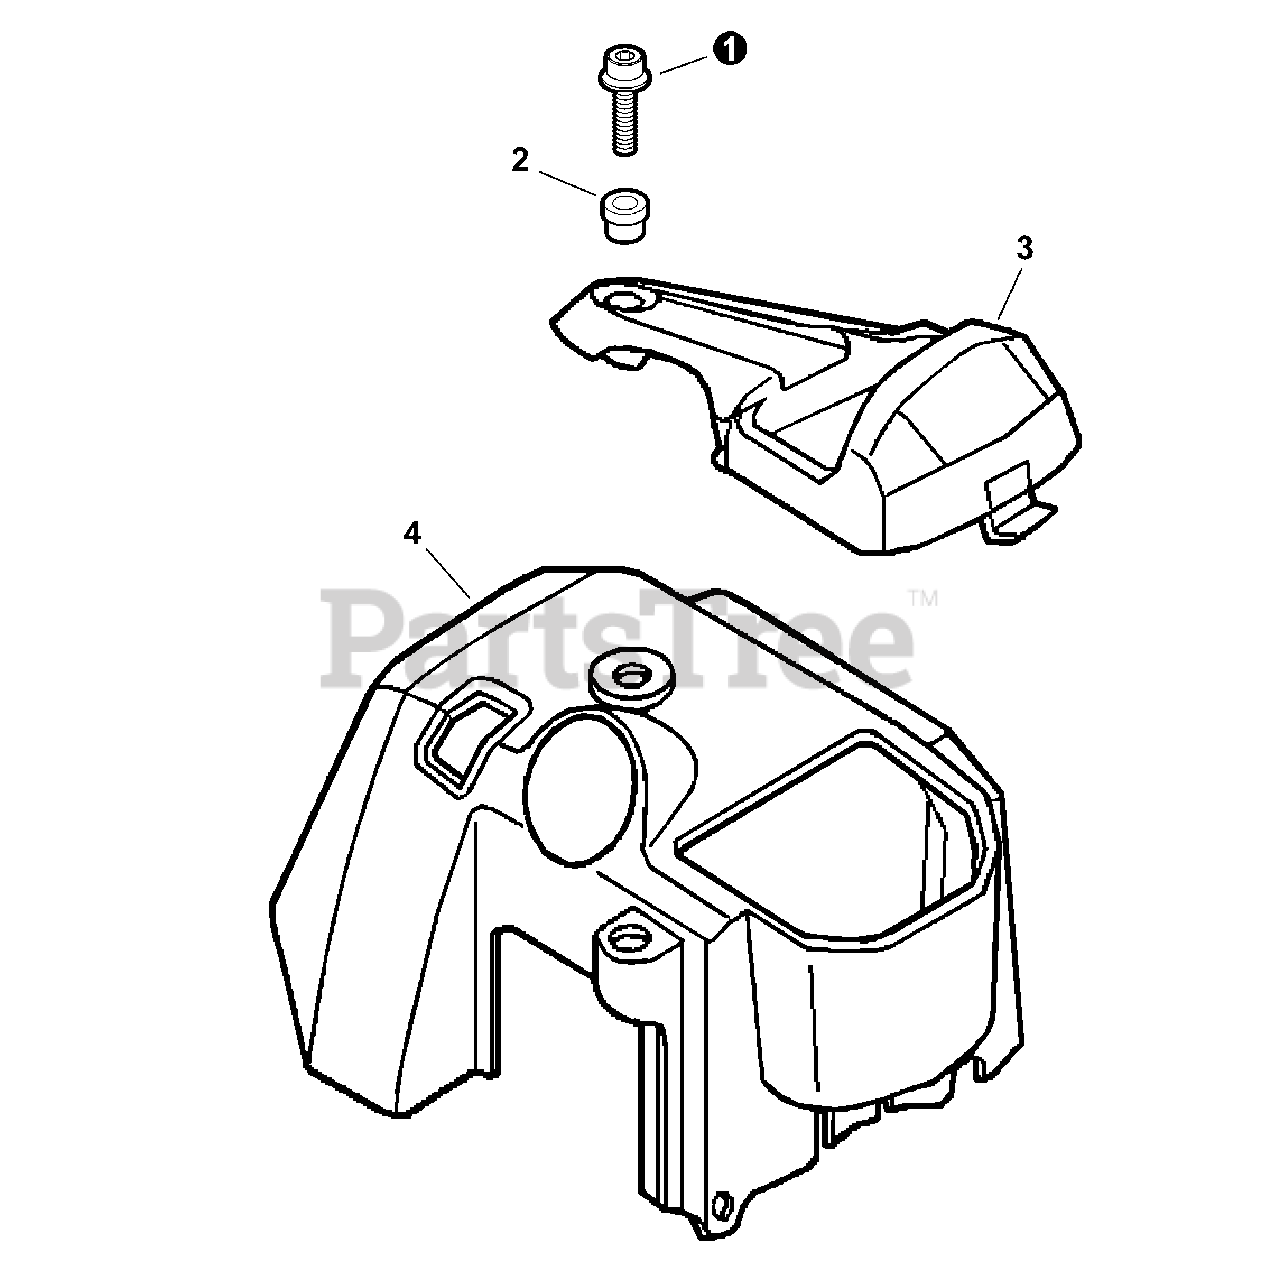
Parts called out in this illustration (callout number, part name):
1	BOLT 5×16
2	COLLAR 5
3	GUARD, TOP - ORANGE
4	COVER, ENGINE - ORANGE
